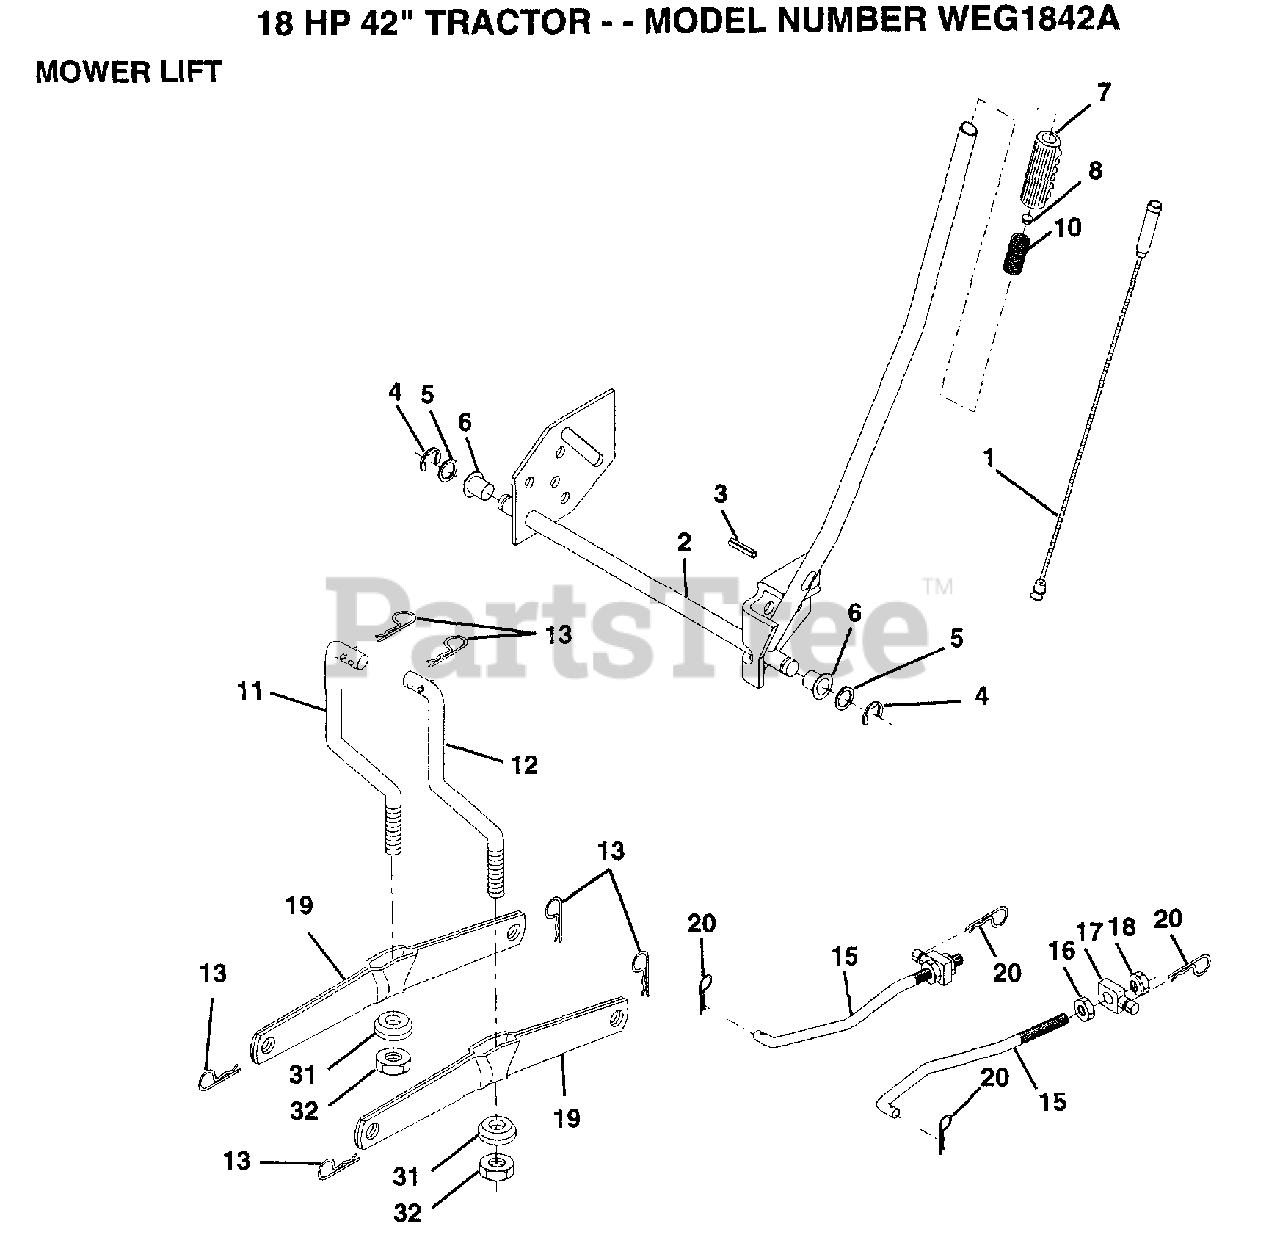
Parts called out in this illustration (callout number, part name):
1	WIRE.ASM.INNER
2	SHAFT.ASM.LIFT.RH
3	PIN GROOVE
5	WASHER
6	NYLON BEARING
7	GRIP
15	LINK.FRONT
16	NUT
17	TRUNION
18	NUT.LK.W/WSH.1/2.
19	ARM SUSP REAR
20	RETAINER.SPRING
31	BEARING PVT LH
32	NUT.LOCK.3/8-24
